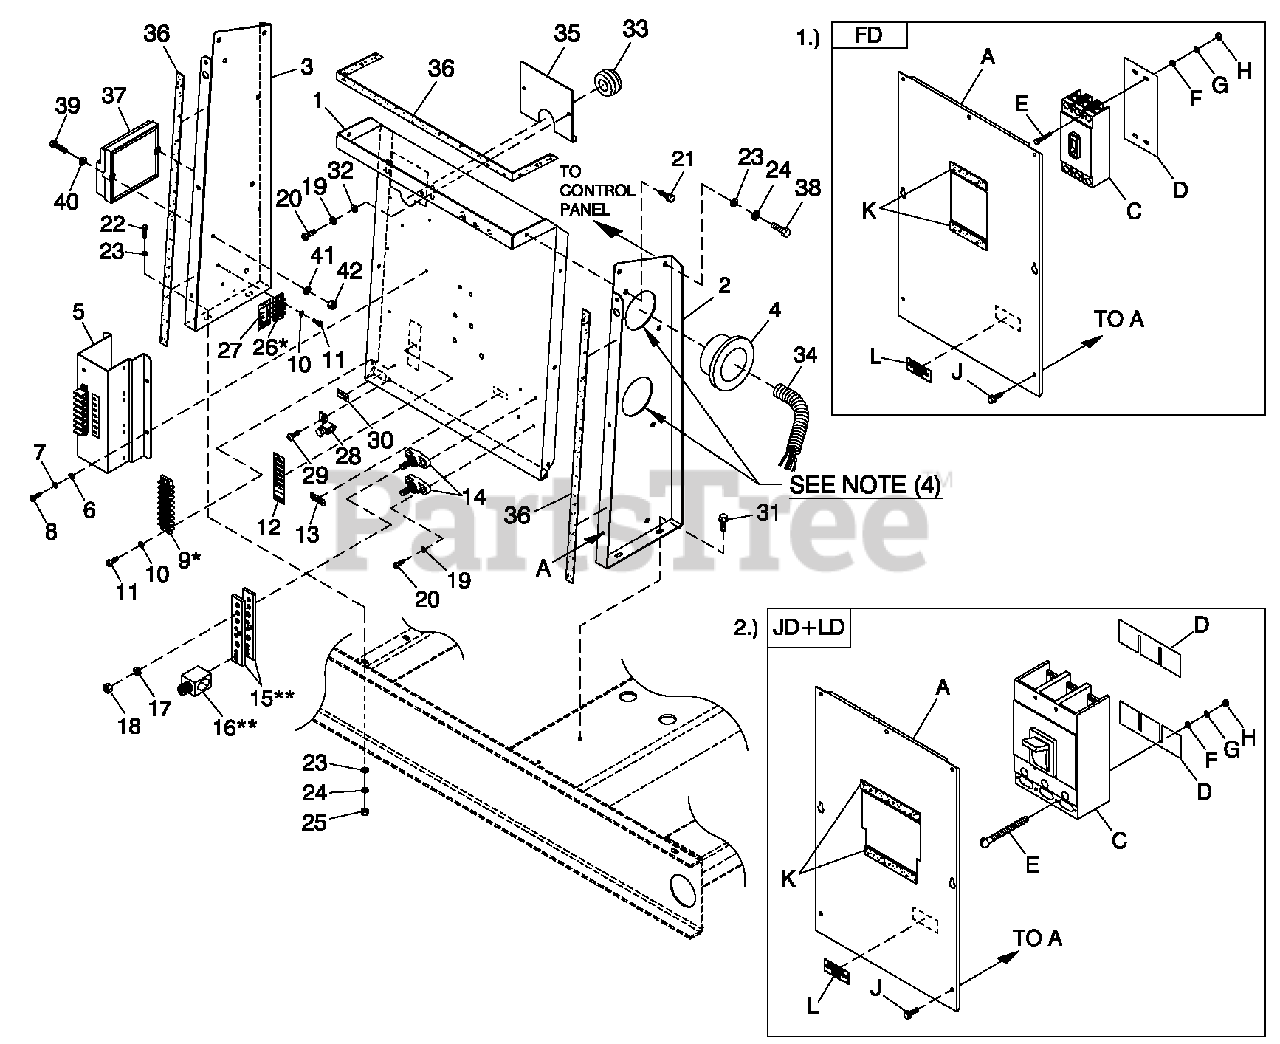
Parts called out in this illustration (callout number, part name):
1	PANEL CB CONN BOX
1	UL CIRCUIT BREAKER (FD)
2	STAND RH CONTROL
2	UL CIRCUIT BREAKER (JD+LD)
3	STAND LH CONTROL C5 GRBX
4	BUSHING SNAP SB-2.5-31
5	INTERFACE 1PH 240V
6	WASHER FLAT M4
7	WASHER LOC K#8-M4
8	SCREW PHTT M4-0.7 X 10 ZYC
10	WASHER LOCK #6
11	SCREW PHTT #6-32 X 1/2 ZYC
12	DECAL CPL CUST CONN H CTRL
13	DECAL NEUTRAL
14	JUNCTION BLOCK 3/8-16
15	BUS BAR NEUTRAL BLOCK 390
16	LUG SLDLSS 600/250-1/0 X 1/4-28
17	WASHER LOCK 3/8
18	NUT HEX 3/8-16 STEEL
19	BLOCK TERM 20A 8 X 6 X 1100V
19	WASHER LOCK M5
20	SCREW PHTT M5-0.8X 16 ZYC
21	SCREW THF M6-1 X 16 N WA Z/JS
22	SCREW HHC M6-1.0 X 20 G8.8
23	WASHER FLAT 1/4-M6 ZINC
24	WASHER LOCK M6-1/4
25	NUT HEX M 6X 1.0 G8 YEL CHR
26	BLOCK TERM 20A 6 X 3 X 1100V
27	DECAL CUST CONN 120V UTILITY
28	LUG SLDLSS #6-14X 13/64CU
29	SCREW HHTT # 10-32X 3/8 CZ
30	DECAL GROUND LUG
31	SCREW HHTT M6-1.0 X 16 ZYC
32	WASHER FLAT M5
33	GROMMET 1.25 X .25 X .75
34	CONDUIT FLEX 2.0" ID
35	PLATE WIRE SNGL GALV
36	TAPE ELEC 1/2 FOAM (AS REQ'D)
37	ASSY PCB 4.6L IGNITION MODULE
38	SCREW HHC M6-1.0 X 16 G8.8
39	SCREW PPHM # 10/32 X 2
40	WASHER FLAT #10 ZINC
41	WASHER LOCK #10
42	NUT HEX #10-32 STEEL
A	COVER FD FRM CB
C	CB 0150A 3P 600V S FD6 LL
D	INSULATOR CB FD FRAME 30MIL
E	SCREW SHC 1/4-20 X 4 G8.8 NZ
F	WASHER FLAT 1/4-M6 ZINC
G	WASHER LOCK M6-1/4
H	NUT HEX 1/4-20 STEEL
J	SCREW THF M6-1 X 16 N WA Z/JS
K	TAPE ELEC 1/2 FOAM (AS REQ'D)
L	DECAL CUSTOMER CONNECT INSIDE
A	COVER CIR BRKR JD/LD
C	CB 0300A 3P 600V S JD6 LL
D	INSULATOR CIRCUIT BR. JD/LD
E	SCREW RHM 1/4 -20 X 3
